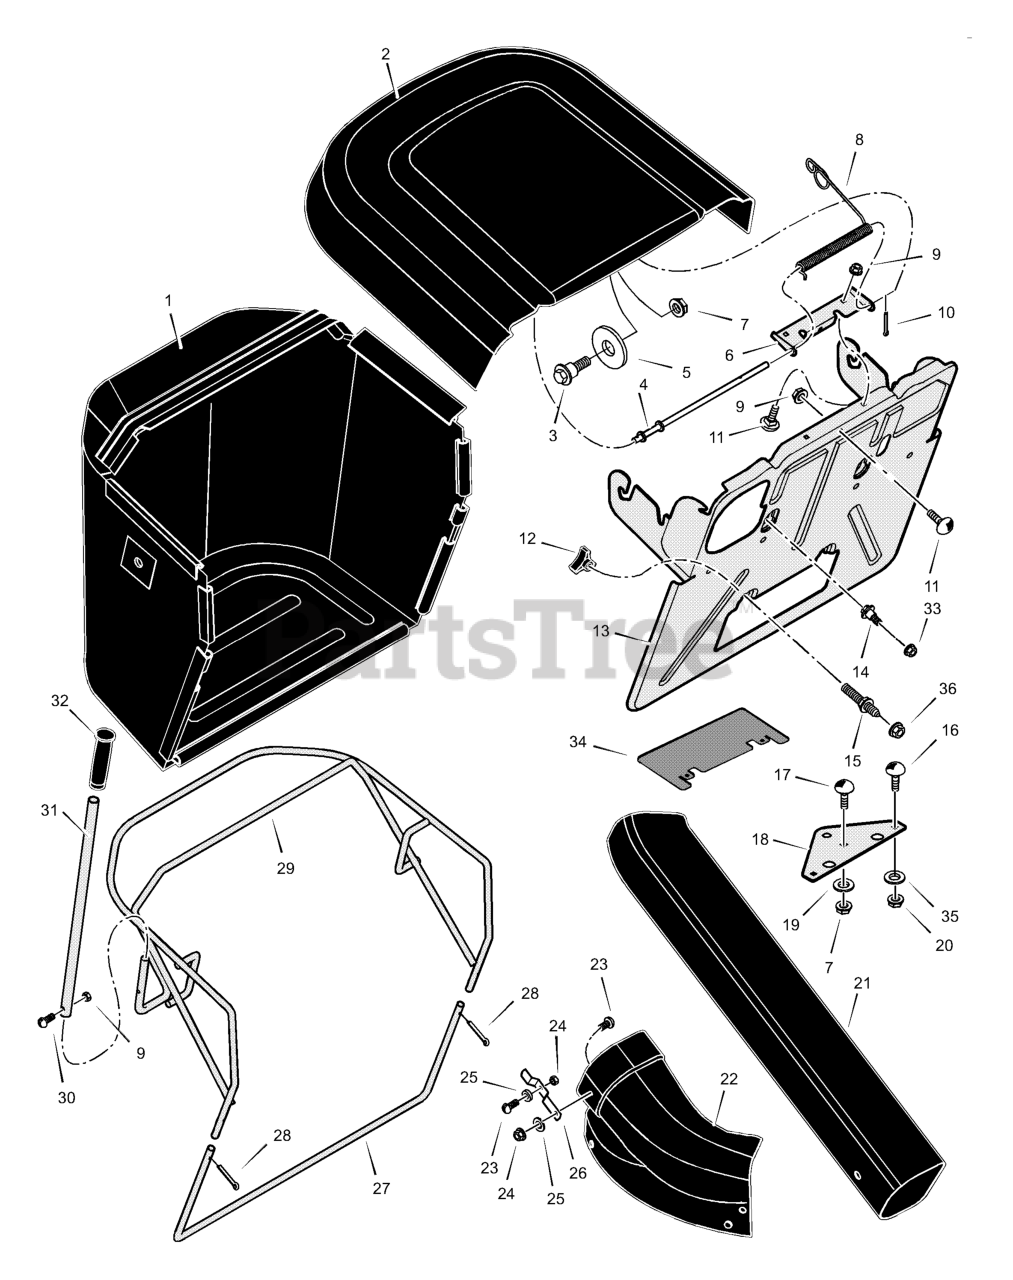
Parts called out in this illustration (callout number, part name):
1	Bag, Cloth
2	Cover, Bag (Green)
3	Bolt, Shoulder
4	Rod, Bag Lid
5	Washer
6	Hinge, Bag Top
7	Nut
8	Spring, Torsion
9	Nut
10	Pin, Cotter
11	Bolt, Carriage
12	Knob
13	Assembly, Bag Plate & Hanger
14	Bolt, Shoulder
15	Stud, Double End
16	Bolt, Carriage
17	Bolt, Carriage
18	Bracket, Hitch Extension
19	Washer
20	Nut
21	Tube, Connecting
22	Tube, Extension
24	Acorn Nut
25	Washer
26	Spring, Leaf
27	Tube, Bag Frame
28	Pin, Cotter
29	Frame, Bag
30	Bolt
31	Lever, Dump
32	Grip
33	Nut, Flange
34	Baffle, Bag Plate
35	Washer
36	Nut
